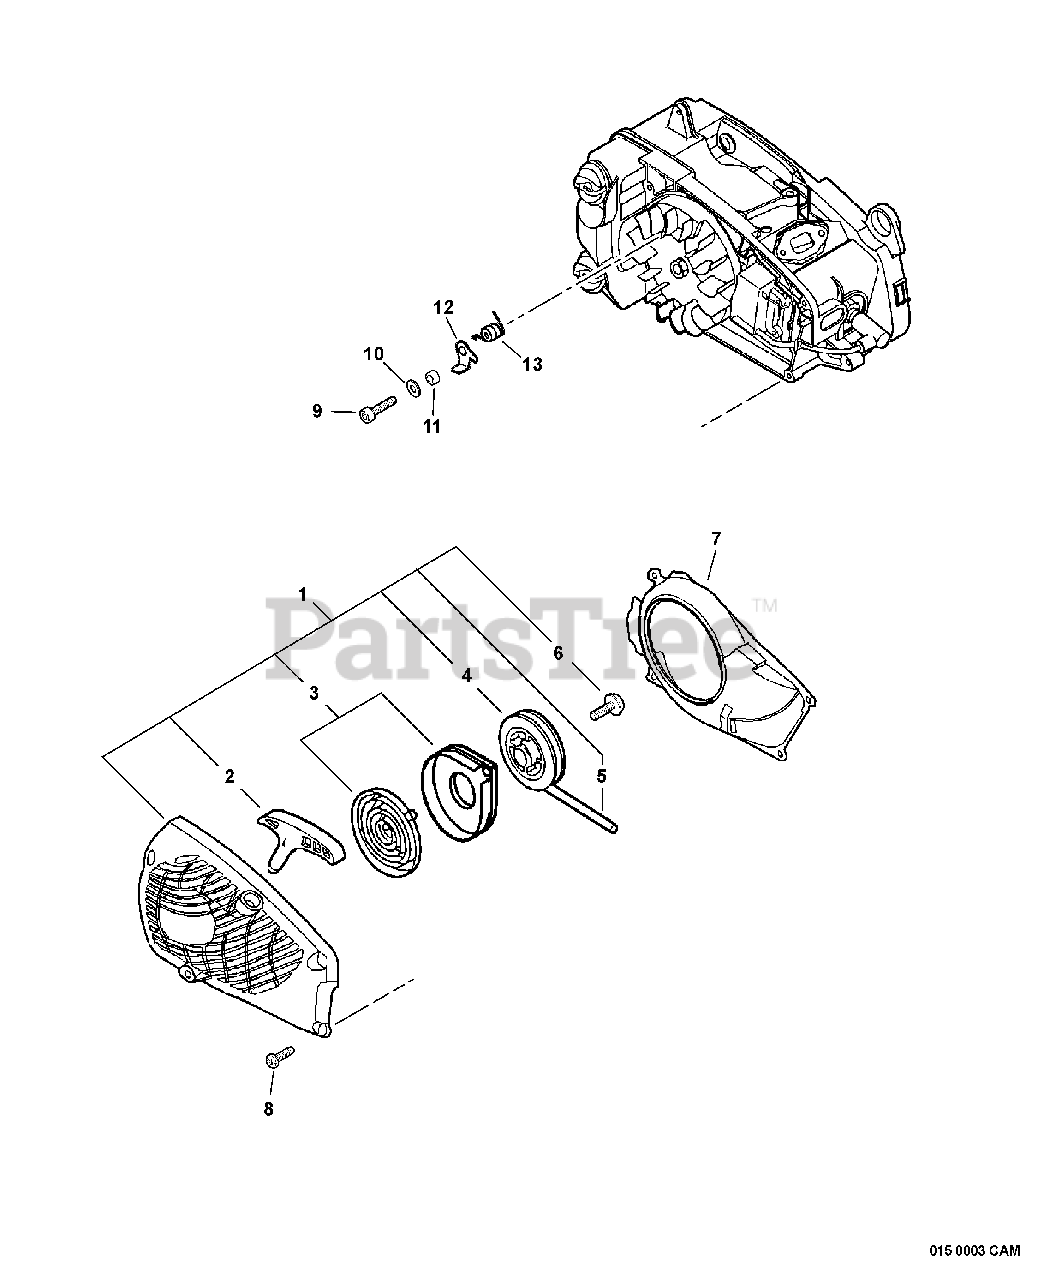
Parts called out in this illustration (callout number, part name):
1	STARTER ASSY, RECOIL
2	GRIP, STARTER
3	SPRING SET, RECOIL
4	REEL, ROPE
5	ROPE, STARTER
6	SCREW
7	COVER, FAN
9	BOLT 5×14
10	WASHER 5.5×12×0.8
11	SPACER 5.2×8×2.1
13	SPRING, TORSION
